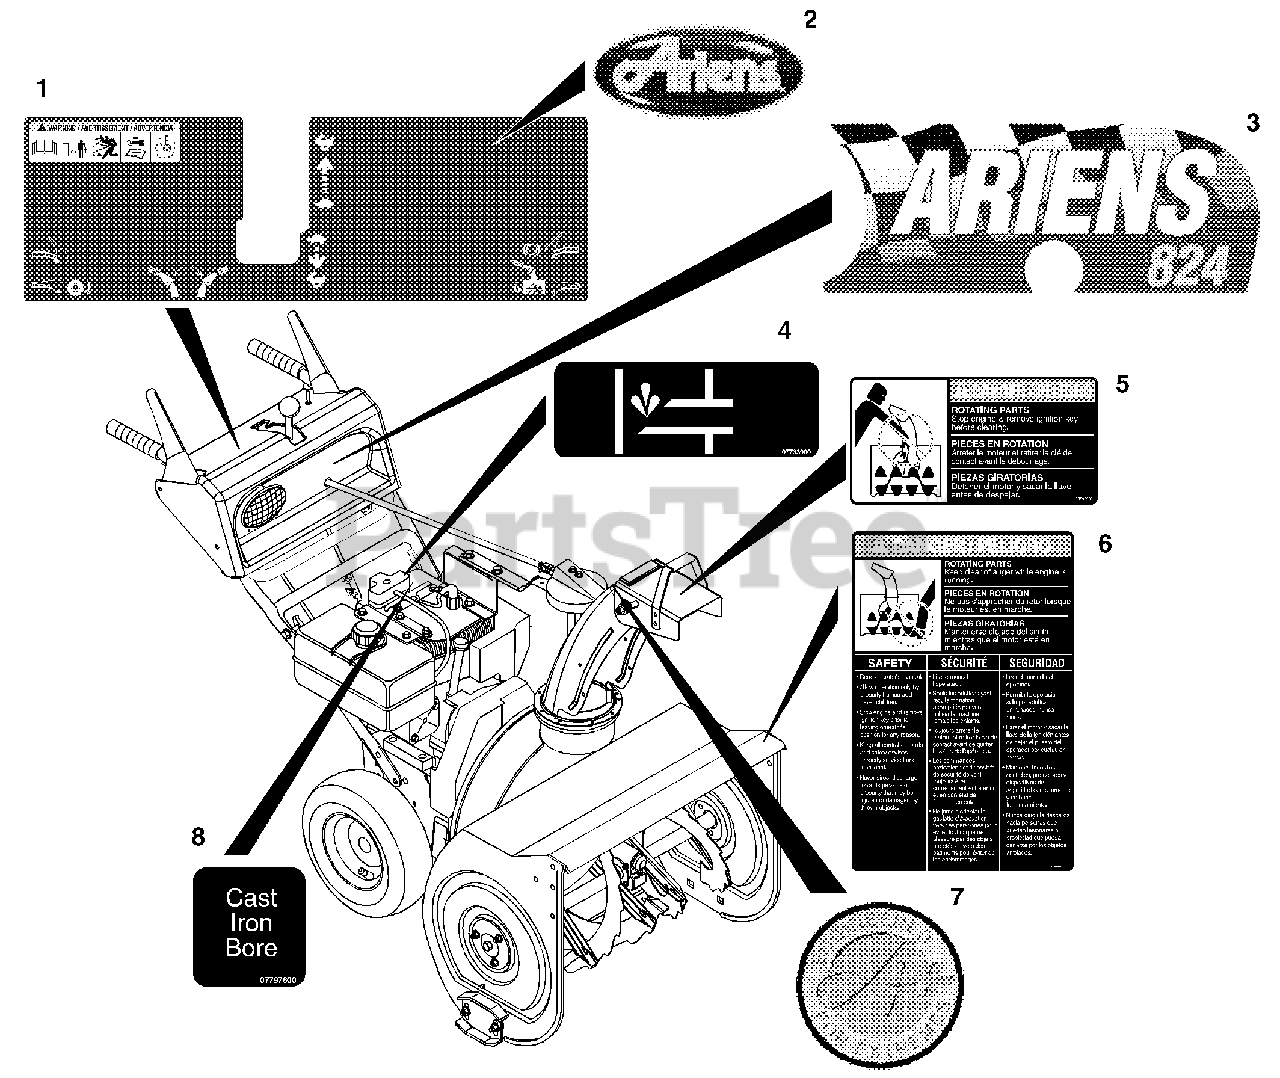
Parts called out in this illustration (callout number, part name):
1	DECAL- CONTROL
2	DECAL, "ARIENS" JEWEL
3	DECAL- FRONT PANEL - 824
4	DECAL, PRIMER "TECUMSEH'S"
5	DECAL, DANGER - ROT. PARTS
6	DECAL, DANGER
7	DECAL, A+
8	DECAL - CAST IRON BORE
